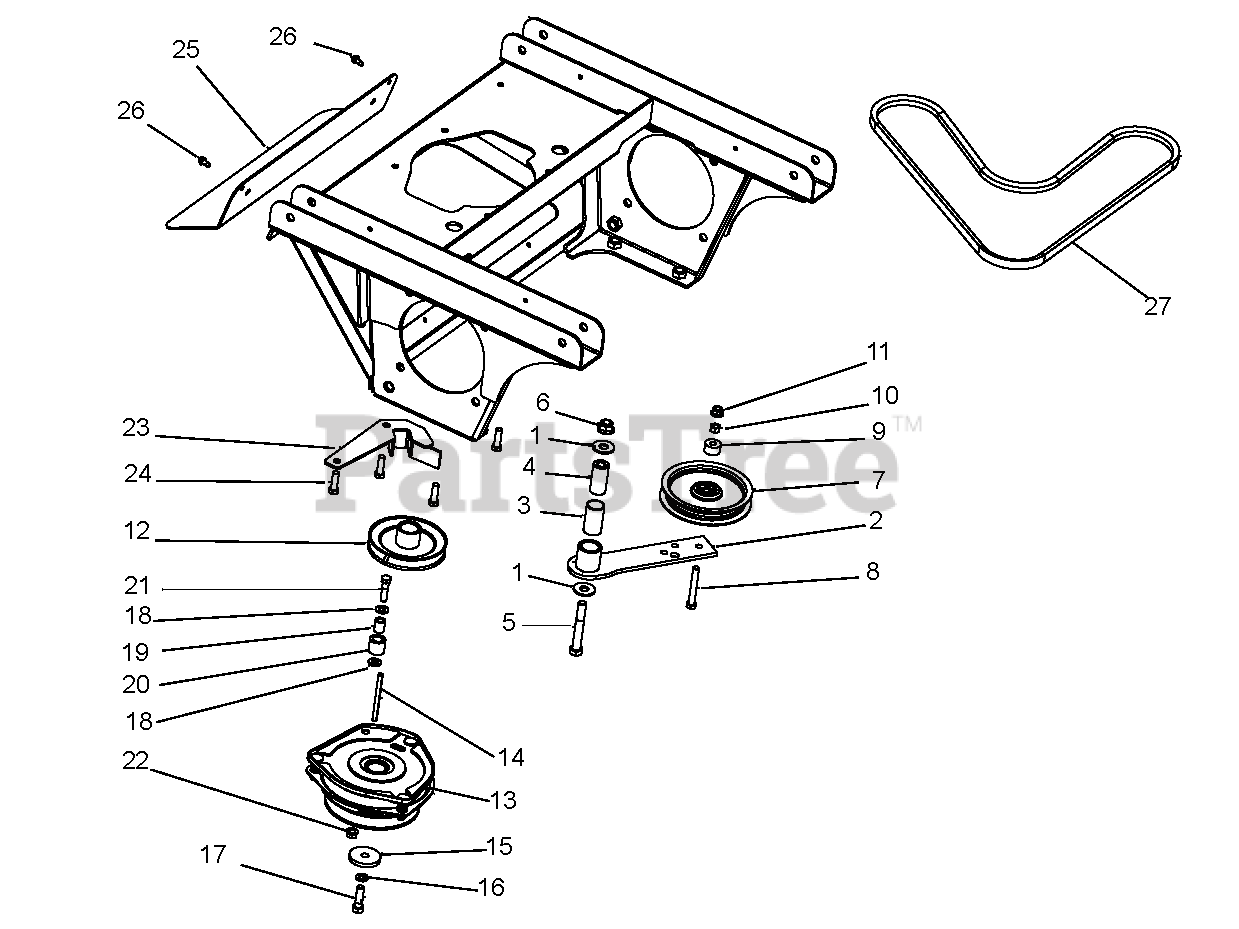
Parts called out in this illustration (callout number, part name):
1	Washer, Flat Steel.563 x 1.38 x .109YWZC
2	Weldment, Idler Arm Ground Drive
3	Bushing, 1.00 x 1.125 x 1.937
4	Bushing, Spacer .502 x .997 x 2.03 PM
5	Bolt, Hex .50-13 x 3.50 GR5 YWZC
6	Nut, Locking Nylon-Flange .50-13 YWZC
7	Idler, Flat 5.00 x .38
8	Bolt, Hex .38-16 x 2.75 GR5 YWZC
9	Spacer .390 x 1.000 x .562
10	Nut, Locking Center .38-16 YWZC
11	Nut, Locking Nylon-Flange .38-16 YWZC
12	Sheave, Engine 5.426 x 1.127
13	Clutch, Electric-OGURA GT3.5-VP01R
14	Key, Square .25 x 3.50 x .25 SAE
15	Washer, Flat Steel .469 x 2.00 x .25 YWZC
16	Washer, Lock .44 x .109 REG YWZC
17	Bolt, Hex .44-20 x 1.50 G5 YZ EP80
18	Washer, Flat Steel.406 x .812 x .065 YWZ
19	Bushing, S.407 x .625 x .813 ST
20	Bumper, Rubber .62 x 1.0 x .88 LG
21	Bolt, Hex .38-16 x 1.50 GR5 YWZC
22	Nut, Locking Top-Flange .38-16 YWZC
23	Weldment, Clutch Stop
24	Bolt, Hex .38-16 x 1.25 FTHG5 EP30YZ
25	Shield, Muffler Heat
26	Screw, Tap .25-20 x .50 Hex Washer Head TR YWZ
27	V-Belt, Cogged B-Raw Edge
